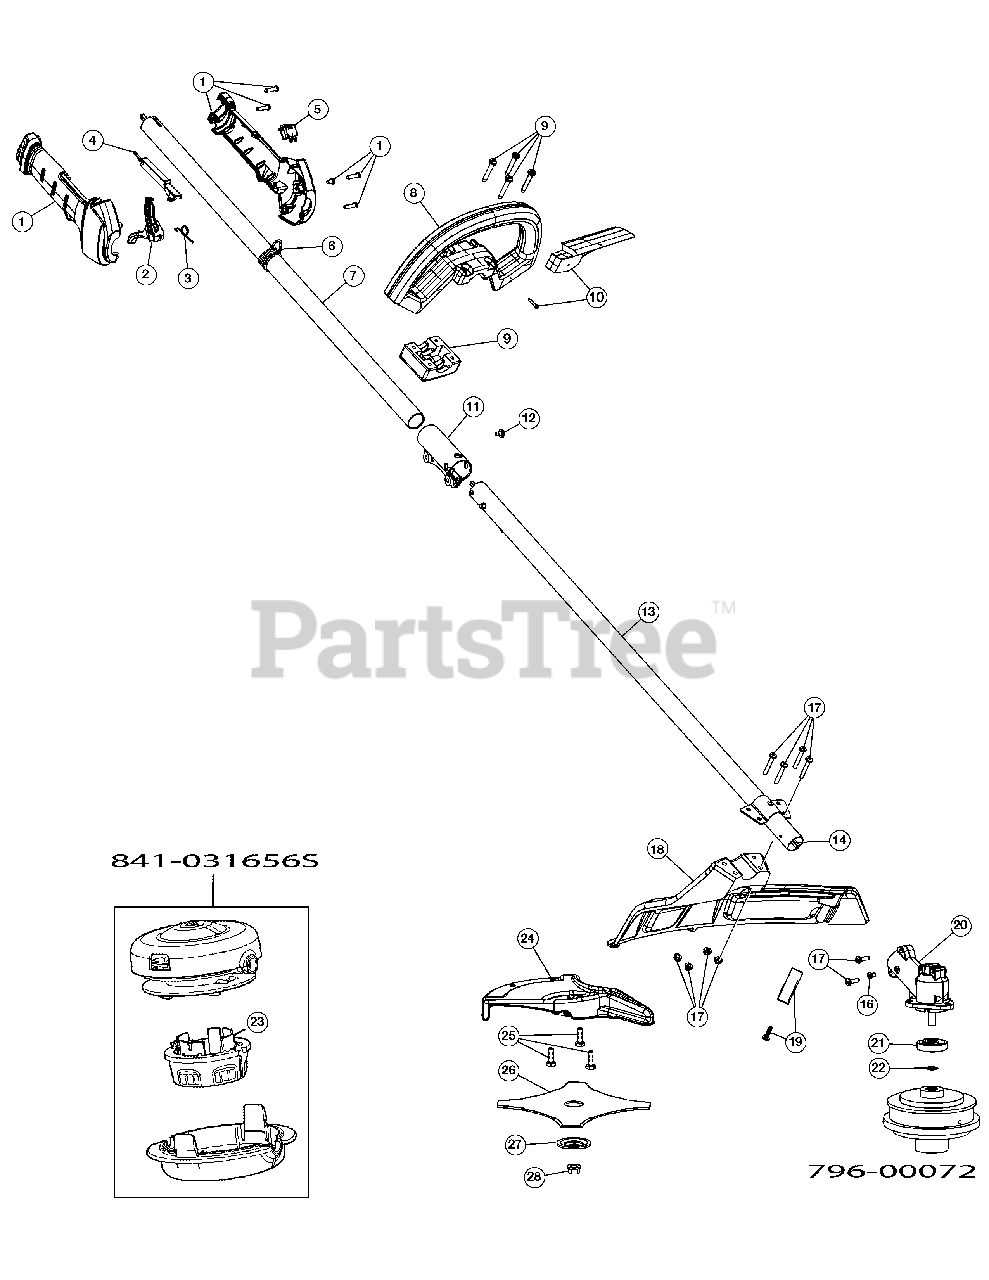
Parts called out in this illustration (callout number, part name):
1	Throttle Housing Assembly
2	Throttle Trigger
4	Throttle Lock-Out
6	Shoulder Strap Clip
7	Upper Driver Shaft Housing Assembly
8	D-Handle Assembly
10	Barrier Bar Assembly
11	Split Boom Coupler
12	Anti-Rotation Screw
13	Lower Drive Shaft Assembly
14	Flexible Drive Shaft
15	Lower Clamp Assembly
16	Anti-Rotation Screw
17	Shield Mounting Screw & Nut
18	Shield Assembly
19	Blade Assembly
20	Gearbox Assembly
21	Blade Driver
24	Blade Shield/Shield Mount
25	Shield Mount Screw Assembly
26	4-Tooth Blade
27	Retaining Washer
796-00072	Cutting Head Assembly
841-031656S	Cutting Head Assembly
